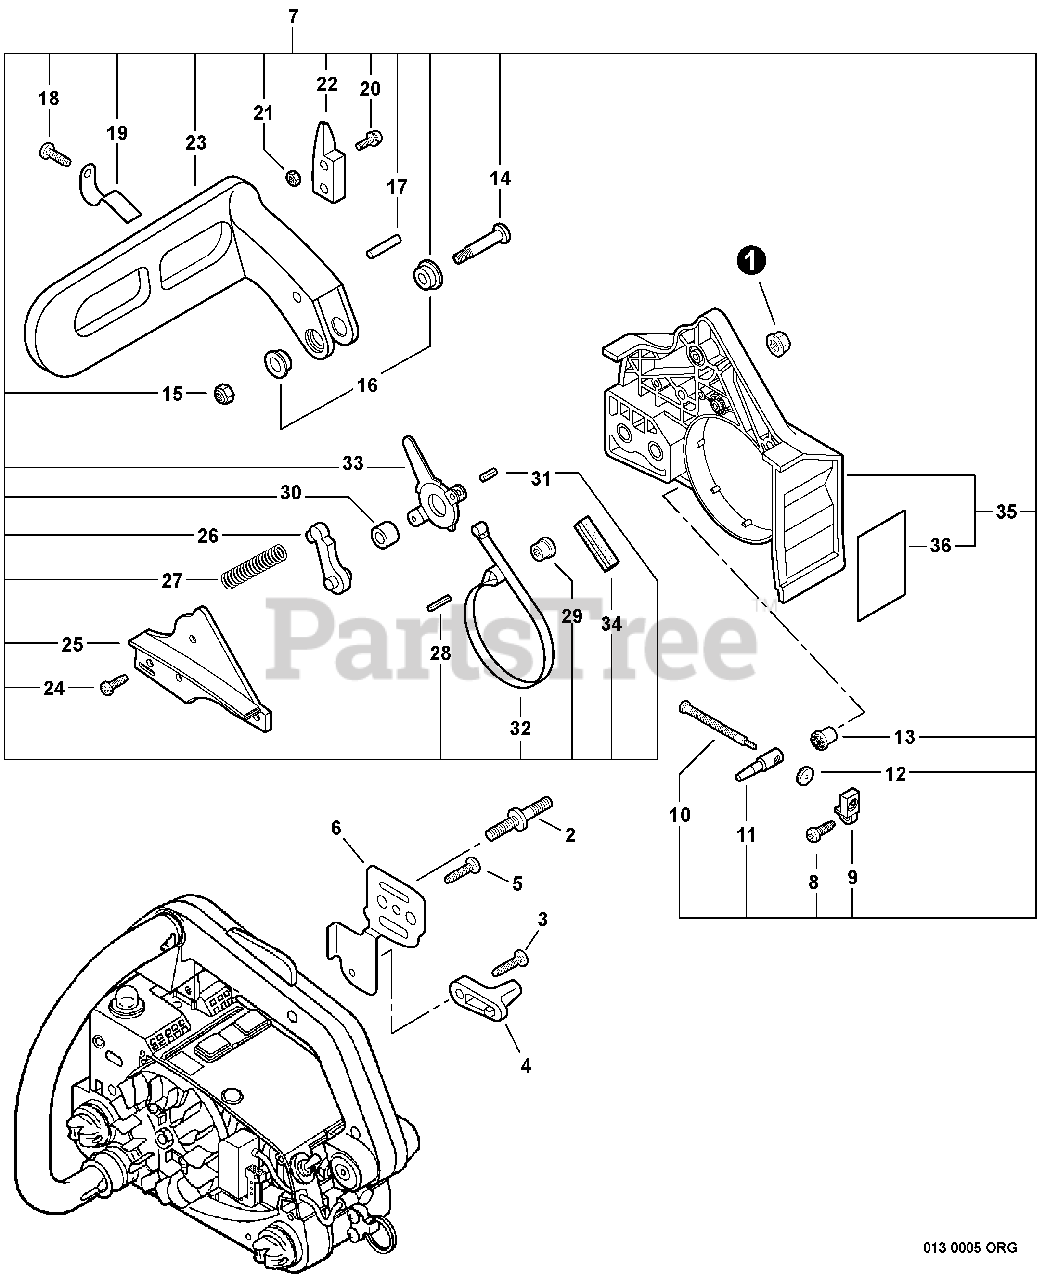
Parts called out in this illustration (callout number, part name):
1	NUT - 6 -- FLANGE
2	STUD, GUIDE BAR
3	SCREW - 5X20 -- TAPPING
4	CATCHER, CHAIN
5	SCREW - 4X10
6	PLATE, GUIDE - OUTER
7	CHAIN BRAKE ASSY
8	SCREW - 4X12 -- TAPPING
9	BRACKET, TENSIONER
10	SCREW, TENSIONER
11	TENSIONER, CHAIN
12	GEAR - BEVEL
13	GEAR - PINION
14	SCREW - 5X32
17	ROLLER - 4X23.8
18	SCREW - 4X10
19	SPRING, RETURN
20	SCREW - 4X20
22	WEIGHT, BRAKE
23	LEVER, BRAKE - BLACK
24	SCREW - 4X12 -- TAPPING
25	COVER, BRAKE - ORANGE
26	STOPPER, BRAKE
27	SPRING, BRAKE
28	PIN - SPRING -- 2.5X12
29	ADJUSTER, BRAKE BAND
30	SPACER - 8
31	PIN - SPRING -- 4X8
32	BAND, BRAKE
33	LEVER, BRAKE
35	GUARD, SPROCKET - ORANGE
36	DEFLECTOR, HEAT
